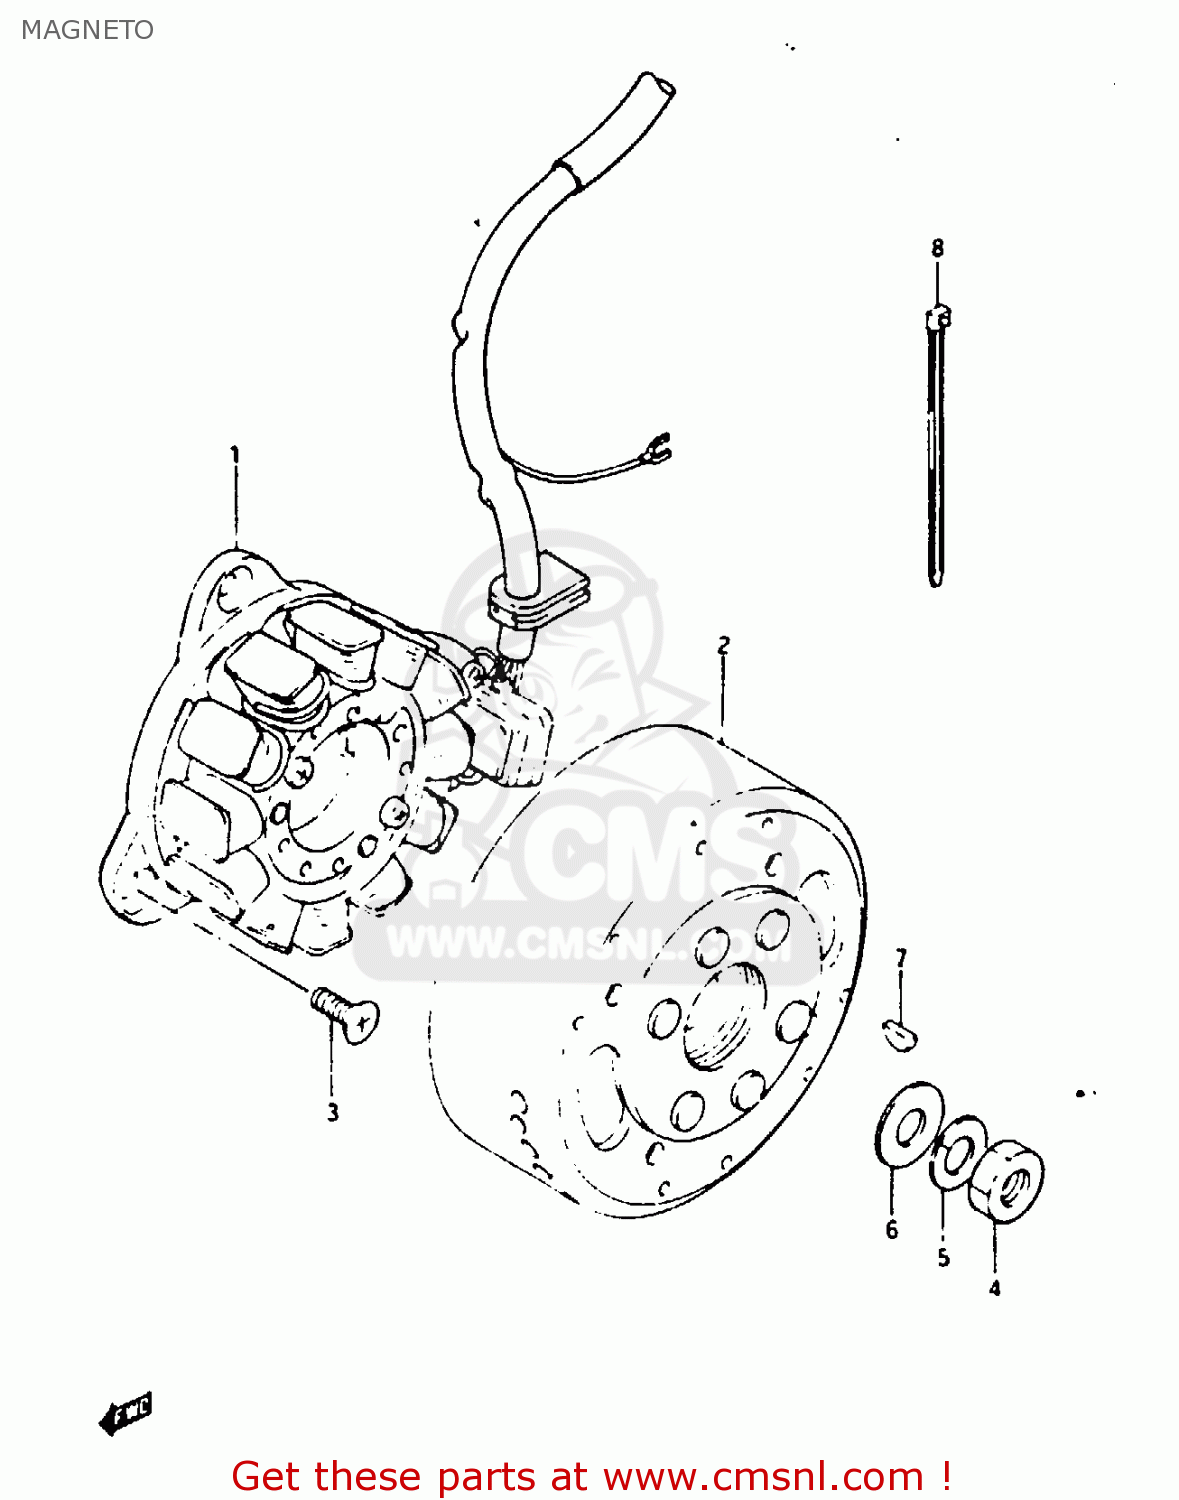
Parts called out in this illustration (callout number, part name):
1	STARTER ASSY
2	ROTOR
3	SCREW
4	NUT (10MM)
5	LOCK WASHER
6	WASHER
7	KEY
8	CLAMP(L:145)
